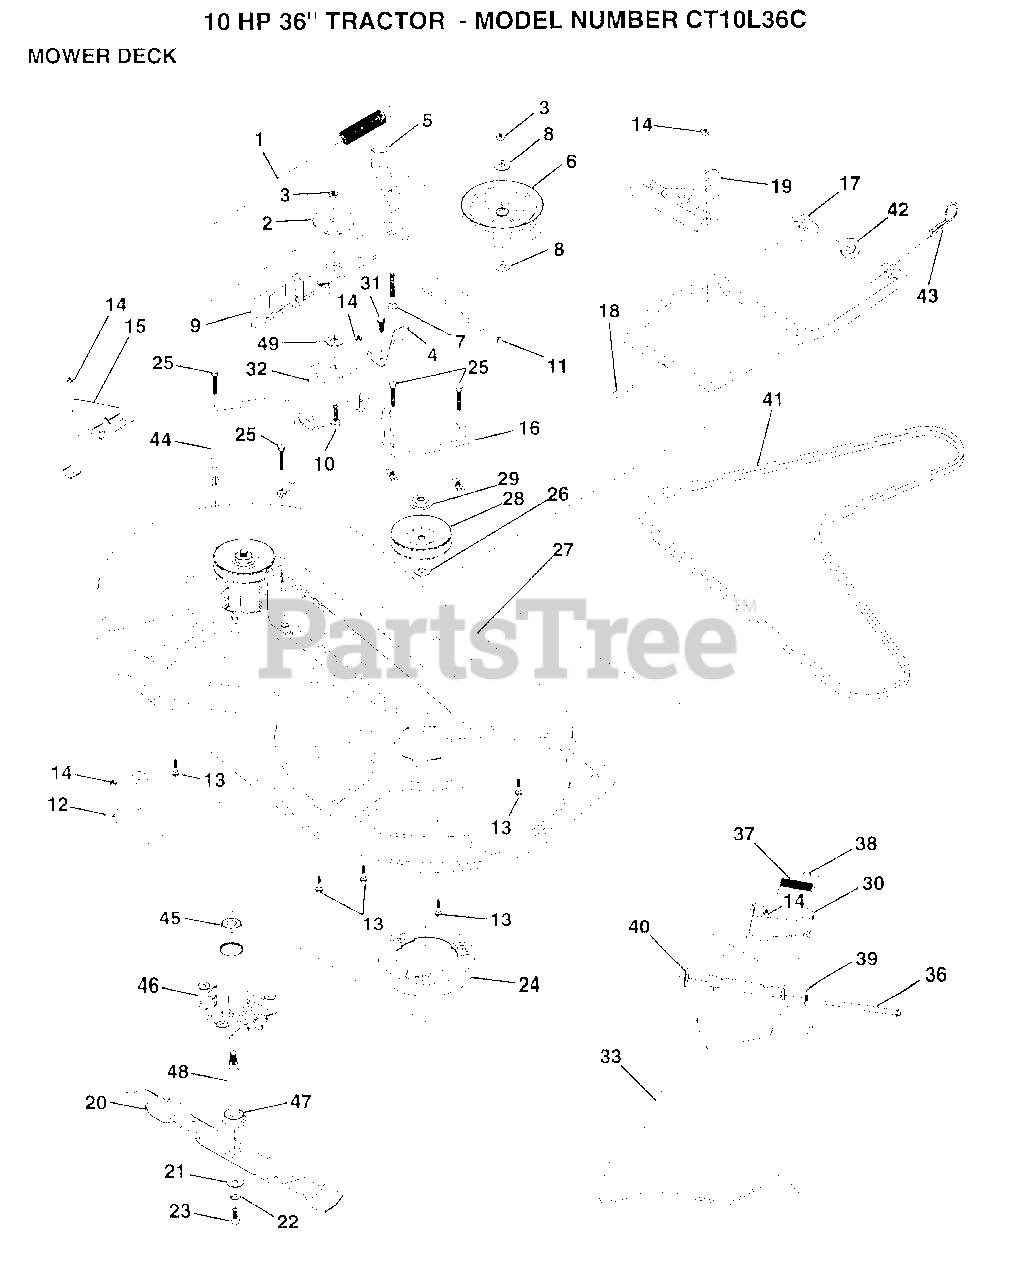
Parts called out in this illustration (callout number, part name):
1	SPRING CLUTCH MWR
2	SPACER RETAINER
3	NUT
4	BRAKE ASM
5	IDLER BELT GUIDE
6	PULLEY IDLER
7	BOLT
8	WASHER
10	BOLT.3/8-14X1.25
11	BRAKE ROD
12	"BRKT,LIFT REAR"
13	BOLT
14	NUT
15	"BRKT,LIFT REAR LH"
17	MOWER LINK STAB
18	"PIN,GROOVE"
19	"BRKT,LINK STABILI"
20	"BLADE MULCH 36"""
21	WASHER.HARD.BLADE
23	BLADE BOLT
24	STRIPPER RND MWR
26	WASHER
31	SCREW LT
32	"SUPT,IDLER ARM"
36	HINGE ROD
37	SPRING TORSION
38	CAP-SLEEVE LT
39	WASHER
40	NUT PUSH M
41	V-BELT.PRIM.78.5.
43	RETAINER.SPRING
44	KEEPER BELT LH
45	BEARING
46	HSG ASM MANDREL
47	BEARING.BALL
49	HARDENED WASHER
